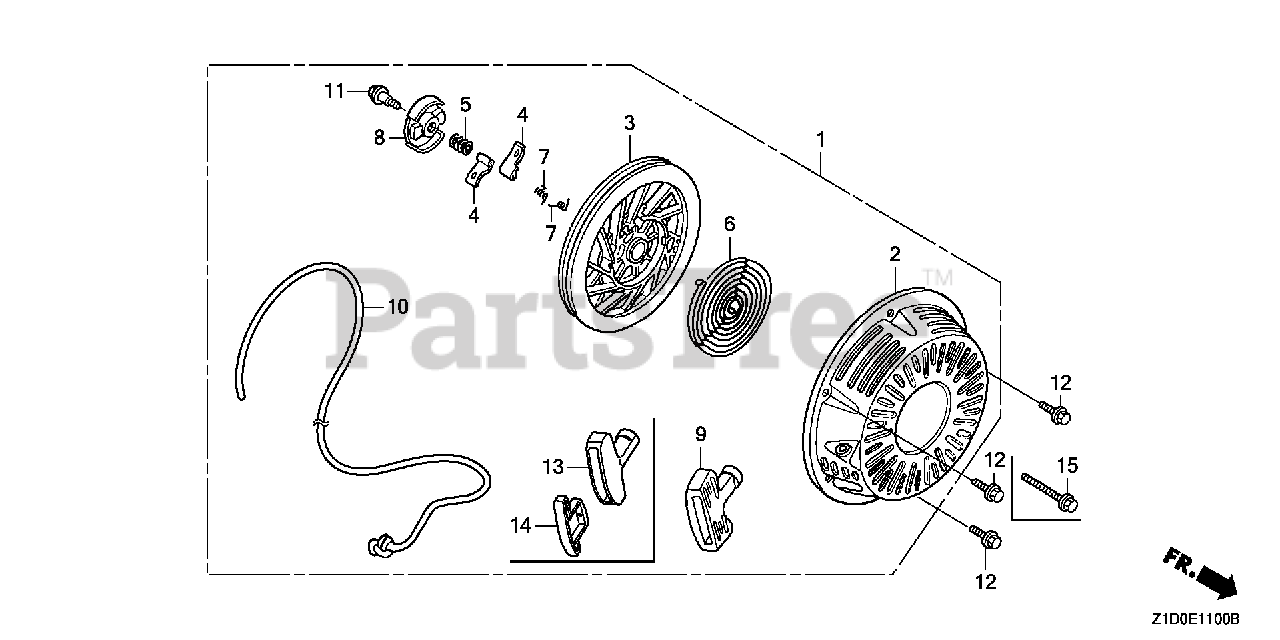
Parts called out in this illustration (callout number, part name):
1	STARTER ASSY., RECOIL *R280* (COO)(FOR U.S.A.) (POWER RED)
1	STARTER ASSY., RECOIL *NH1* (COO)(FOR U.S.A.) (BLACK)
2	CASE, RECOIL STARTER *R280* (POWER RED)
2	CASE, RECOIL STARTER *NH1* (BLACK)
3	PULLEY, RECOIL STARTER
4	RATCHET, STARTER
5	SPRING, FRICTION
6	SPRING, STARTER RETURN
7	SPRING, RATCHET
8	RETAINER, SPRING
10	ROPE, RECOIL STARTER
11	SCREW, CENTER
12	BOLT, FLANGE (6X10)
13	GRIP, STARTER
13	GRIP, STARTER (COO)(FOR U.S.A.)
14	GRIP, REINFORCEMENT
